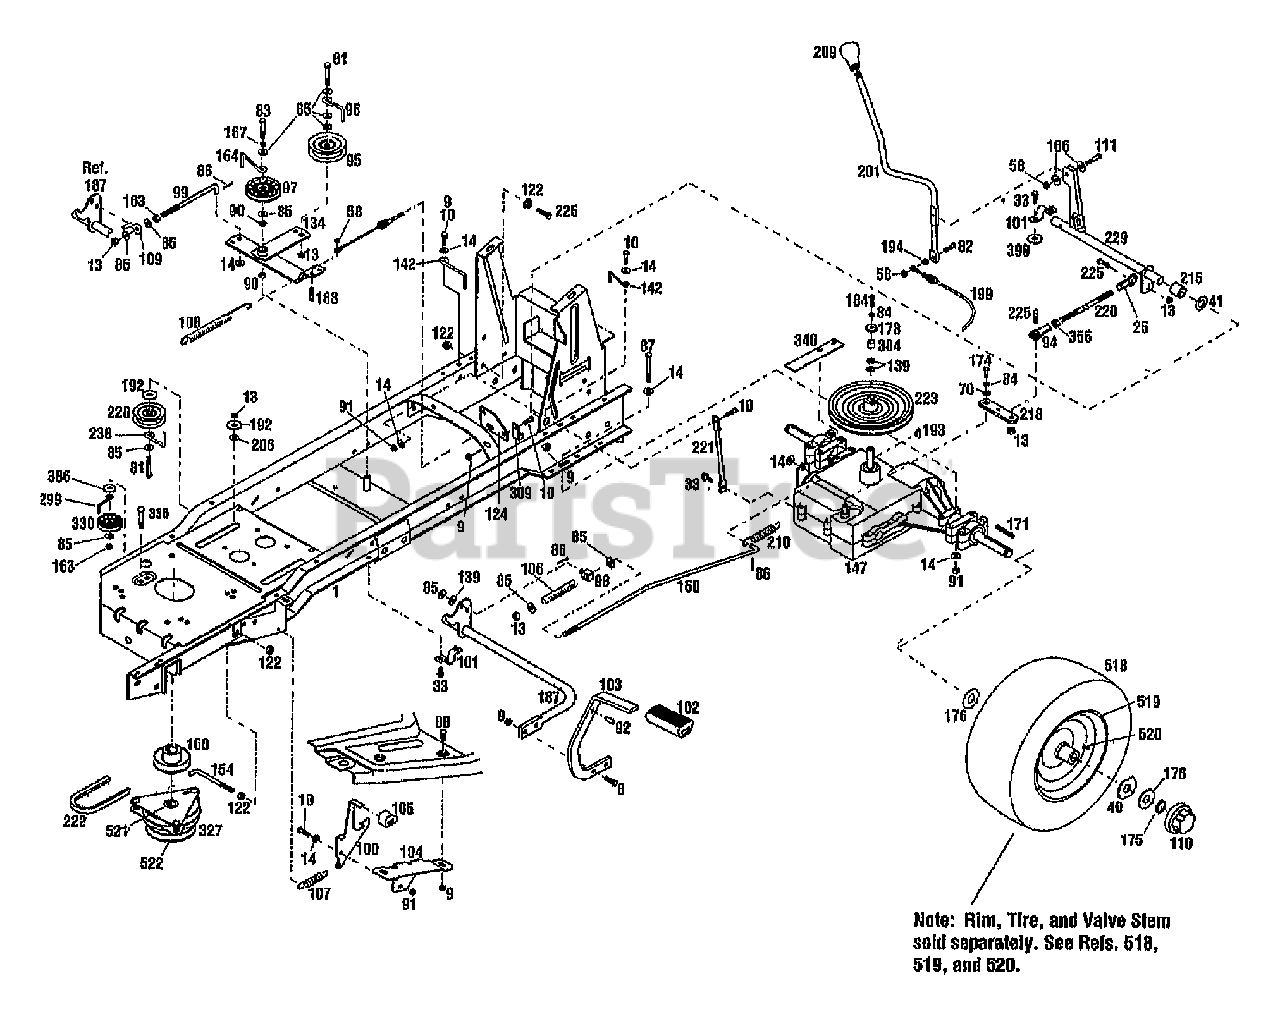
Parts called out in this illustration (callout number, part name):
1	ASSM-FRAME LTX
8	SCR-HH 5/16-18X1.0 G5 ZP
9	NUT-HFLK 5/16-18 ZP
10	SCR-HHC 5/16-18X.75 GR 5 ZP
13	NUT-LOCK 3/8-16
14	WASHER-FLAT 5/16 SAE
25	JOINT-BALL
33	SCR-HFLK 5/16-18X.75
40	WASHER-SPEC .75X2.50
41	WASHER-THRUST
58	NUT-HT LK 1/4-20
70	WASHER-FLAT 1/4 SAE
81	SCR-HH 3/8-16X2.0 G5 ZP
82	SCR-HH 1/4-20X1.0
83	SCR-HH 3/8-16X1.75 G5 ZP
84	WASHER-LK .25 ZP
85	WASHER-FLAT 3/8 SAE
86	PIN-COTTER .09X.75 ZP
87	SCR-HH 5/16-18X2.75 G5 ZP
88	SCR-CARR 5/16-18X.62 G2 ZP
90	BUSHING-.5X.5 NYLON FLNG
91	NUT-TOP/LK 5/16-18 ZP
92	PIN-DRIVE .312X.75
94	JOINT-BALL
96	GUIDE-BELT
97	PULLEY-IDLER
98	SWIVEL
99	ROD-CLUTCH
100	LATCH-BRAKE CLUTCH USE1771514
101	CLIP-CLAMP .75 ID
102	PAD-FOOT PEDAL
103	PEDAL-BRAKE
104	BRKT-BRAKE LOCK
105	PAD-BRAKE
106	SPRING-COMPRESSION
107	SPRING-EXTENSION
108	SPRING-EXTENSION
109	ROD-PIVOT
110	CAP-HUB
111	SCR-HFLK 1/4-20X1.00
122	NUT-HFLK 3/8-16 ZP
124	SUPPORT-CABLE
134	PLATE-IDLER
139	WASHER-FLAT .375DIA
142	GUIDE-BELT
147	TRANSAXLE
154	RETAINER-CLUTCH
160	PULLEY-ENGINE
163	NUT-HEX 3/8-16 ZP
164	GUIDE-BELT
166	WASHER-FLAT 1.25X.28X.062 ZP
167	WASHER-LK .375 @ DEPL
168	SCR-HH 1/4-20X.75 G5 ZP
171	KEY-.188 SQ X 2.0
173	WASHER-.865X.281X.1793
174	SCR-HHC 1.4-28 X .50
175	RING-RET."E".577 ID
176	WASHER-1.87X.765X.06 SPECIAL
184	SCR-HH 1/4-20 X .875
187	ASSM-BRAKE PEDAL
192	WASHER-1.12X.378X.125
193	KEY-WOODRUFF .188X.75
194	NUT-HEX 1/4-20 ZP
199	CABLE-SHIFT
201	ARM-SHIFT
210	SPRING-EXTENSION
215	SPACER
218	ARM-TRANSMISSION
220	ROD-ADJUSTING
221	SUPPORT-TRANS
223	PULLEY-TRANSMISSION
225	SCR-HH 3/8-16X1.25
228	IDLER-SHEAVE 3" X 1"
229	SHAFT-PIVOT
238	GUIDE-BELT
286	WASHER-.75X.406X.092
299	GUIDE-BELT
309	CLIP-J
327	CLUTCH-ELECTRIC
330	PULLEY-IDLER
336	BOLT-CARR
340	STOP-TRANSMISSION
356	NUT-HEX/JAM 3/8-24 ZP
384	SPACER-625X.376X.625
386	WASHER-1.06X.531X.1 ZP
390	WASHER-.632X.39X.0329
518	TIRE-20X8.00-10
519	DISC-WHEEL
520	STEM-VALVE
